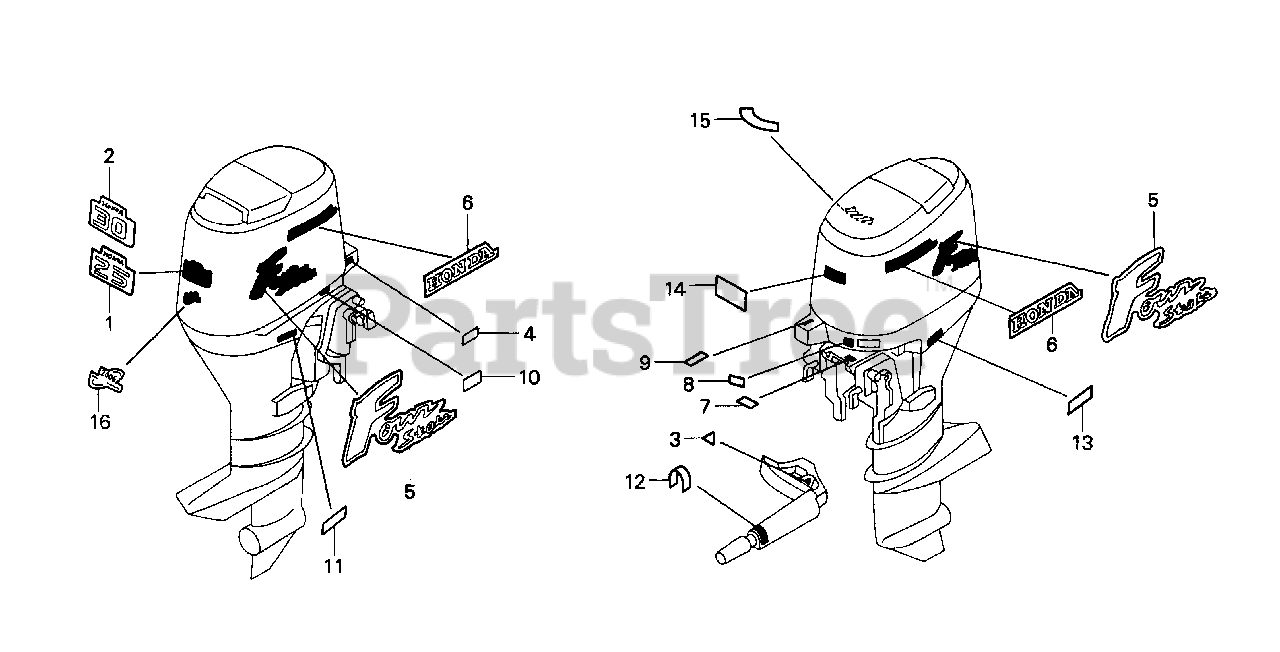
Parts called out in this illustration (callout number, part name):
3	MARK, EMERGENCY SWITCH INDICATION (ENGLISH)
5	MARK, SIDE
6	MARK, SIDE STRIPE
7	LABEL, SPECIFICATION (NMMA)
8	MARK, OIL PRESSURE
9	MARK, CHANGE (ENGLISH)
10	MARK, RECEPTACLE (10A)
11	LABEL, OIL CAUTION (ENGLISH)
12	MARK, THROTTLE (ENGLISH)
13	LABEL, STORING CAUTION (ENGLISH)
14	LABEL, CAUTION OPERATOR (ENGLISH)
15	MARK, EMERGENCY START (ENGLISH)
16	MARK, ENVIRONMENT (EPA 2006)
